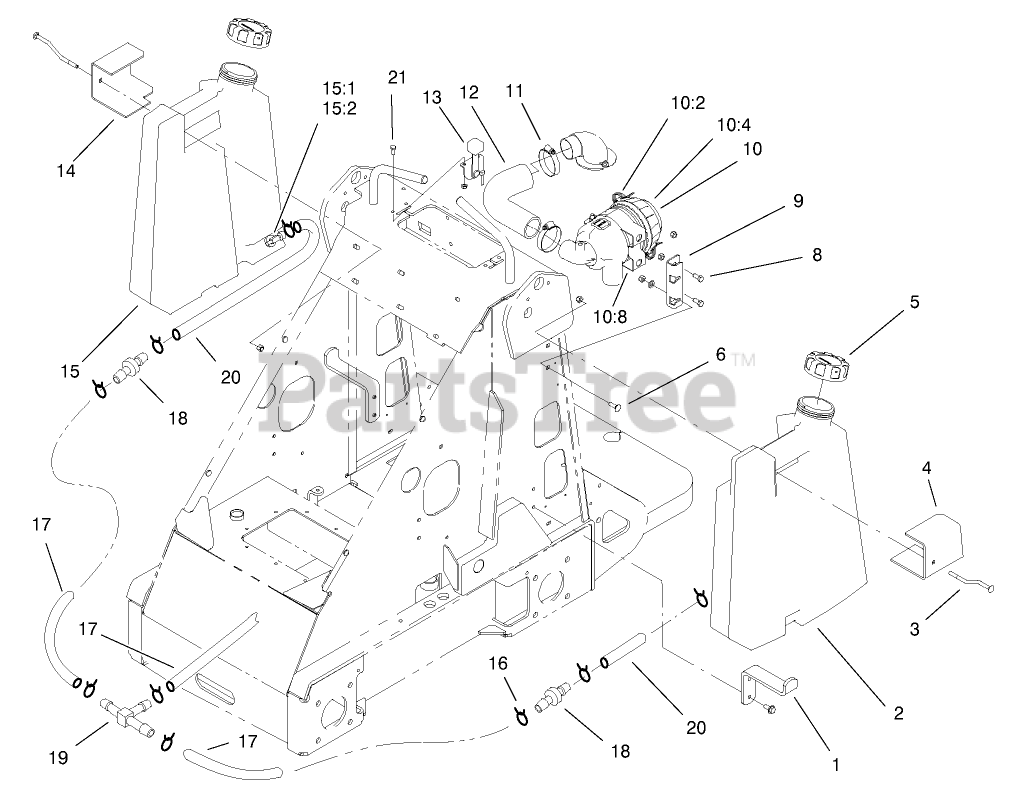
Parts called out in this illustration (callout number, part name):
1	MOUNT-BOTTOM, TANK
2	Fuel Tank ASM
3	BOLT-MOUNT
4	PLATE-MOUNT, LEFT
5	GAS CAP ASM
6	BOLT-CARR
8	SCREW-HH
9	MOUNT-CLEANER, AIR
10	AIR CLEANER ASM
10:2	CLIP-CLEANER, AIR
10:4	COVER
10:8	MOUNTING BRACKET ASM
11	CLAMP-HOSE
12	HOSE-AIR
13	CONTROL-CHOKE / THROTTLE
14	PLATE-MOUNT
15	Fuel Tank ASM
16	CLAMP-HOSE
17	HOSE-FUEL
18	VALVE-CHECK, FUEL
19	FITTING-TEE, BARBED
20	HOSE-FUEL
21	SCREW-HHF
